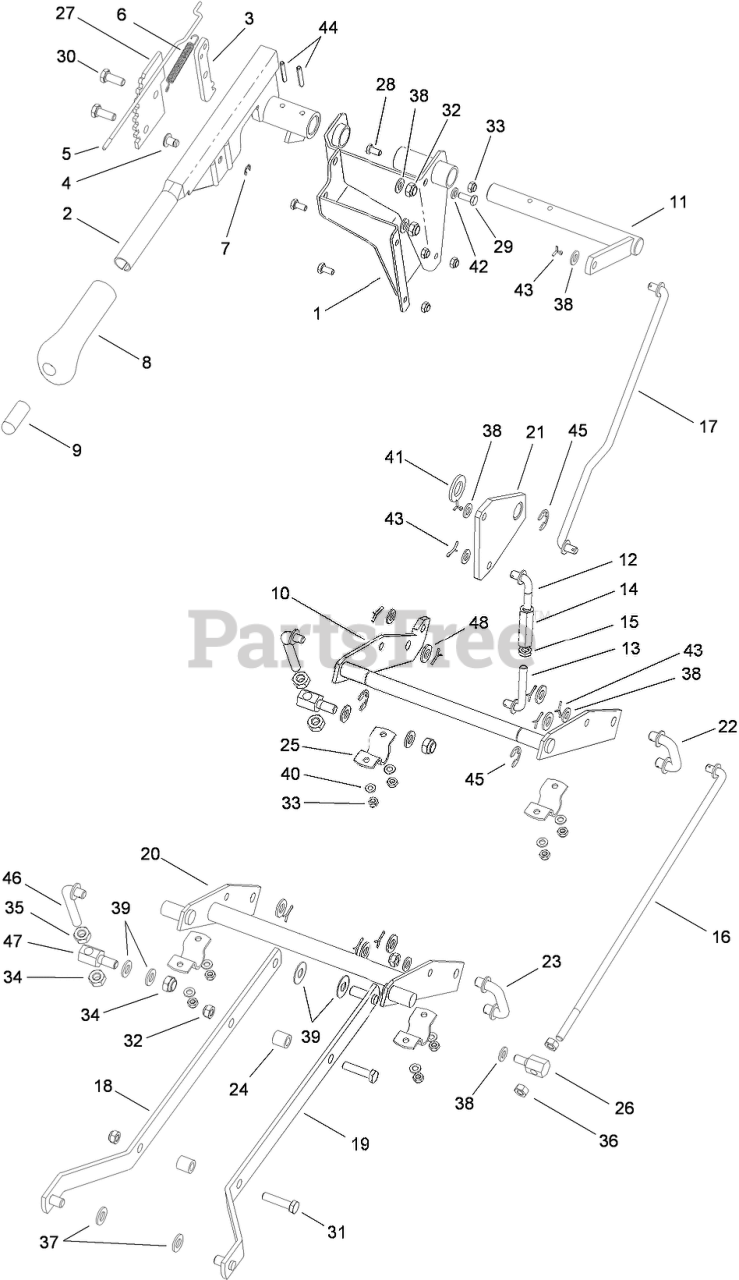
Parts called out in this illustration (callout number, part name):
1	BRACKET
2	LEVER ARM
3	RATCHET-PLATE, PIVOT
4	PIN-LEVER, ARM
5	ROD-CONNECTION
6	SPRING
7	CLIP-PIN
8	GRIP-HANDLE
9	BUTTON-PLUNGER
10	HANGER-REAR
11	SHAFT-ADJUSTMENT, HEIGHT
12	ROD-TOP
13	ROD-LOWER
14	NUT-TURNBUCKLE
15	NUT-HEX
16	ROD-LINKAGE
17	ROD-LINKAGE
18	BRACKET-RIGHT DECK SUPPORT
19	BRACKET-LEFT DECK SUPPORT
20	HANGER-FRONT
21	BRACKET-LINKAGE
22	DECK LINK, U-SHAPE, 50
23	DECK LINK, U-SHAPE, 55
24	SPACER
26	TRUNNION
27	GEAR-SECTOR
28	SCREW-HH
29	SCREW-HH
30	SCREW-HH
31	SCREW-HH
32	NUT-LOCK, NI
33	NUT-LOCK
34	NUT-LOCK, NI
35	NUT-HEX
36	NUT-HEX
37	Washer
38	WASHER-PLAIN
39	WASHER-FLAT
40	WASHER
41	WASHER-FLAT
42	WASHER-SPRING
43	PIN-COTTER
44	PIN-SPRING
45	E-CLIP
46	LINK-DECK, L-SHAPE (ADJUSTABLE)
47	TRUNION
48	WASHER-PLAIN
